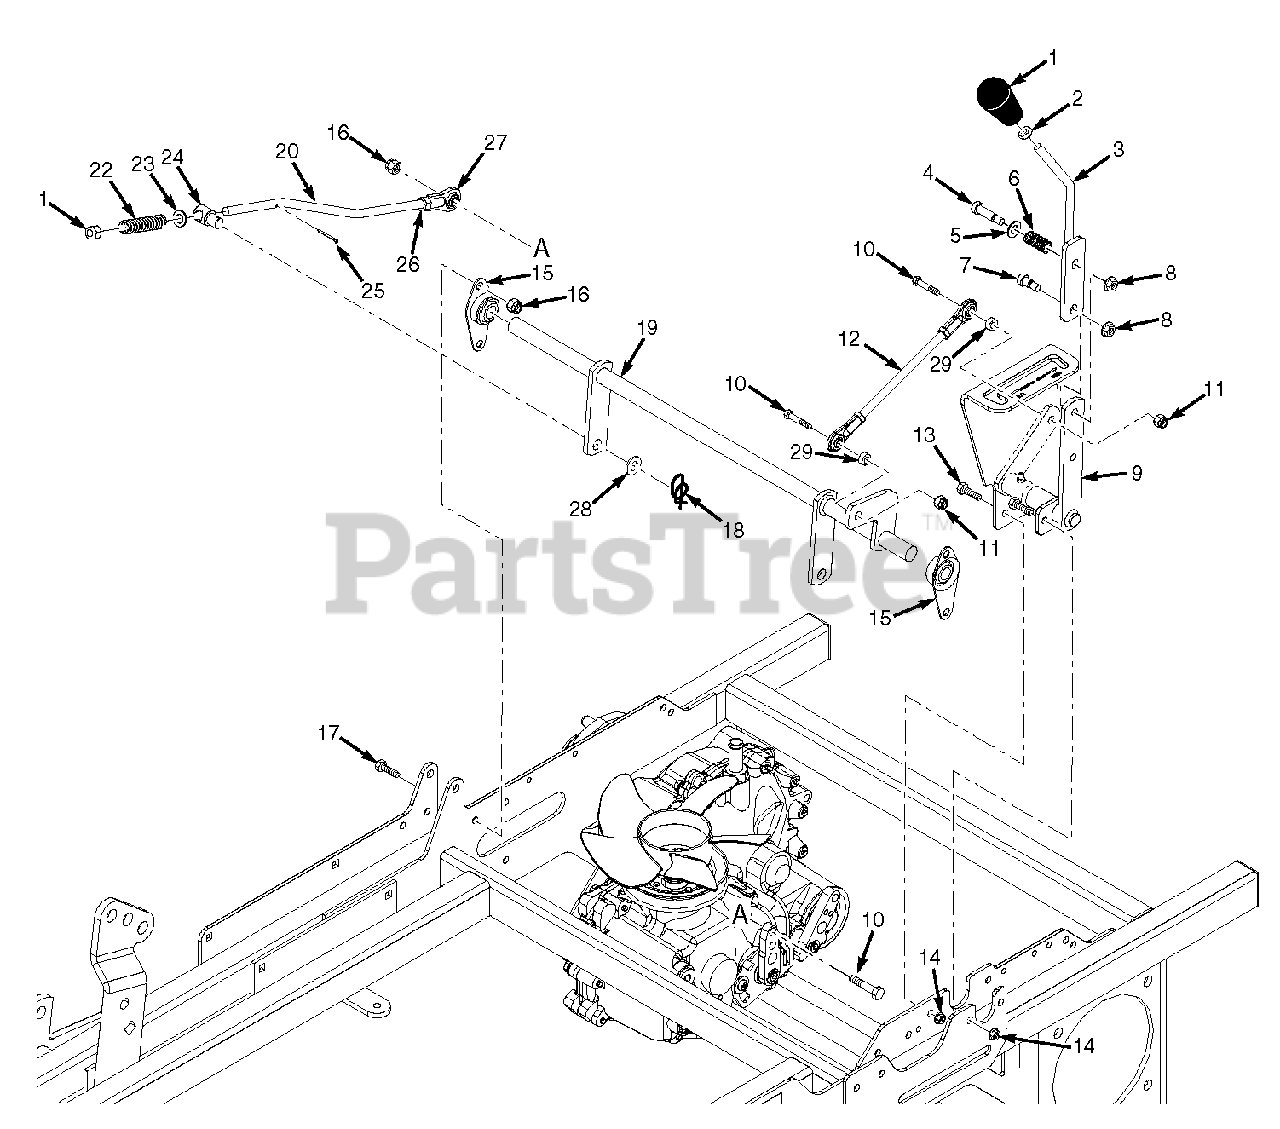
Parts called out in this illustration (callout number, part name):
1	Knob, Soft Touch
2	Nut, Jam 3/8-16 UNC
3	Lever Weldment, Speed Control SCZ
4	Bolt, Shoulder 3/8 x 1"
5	Flatwasher, 3/8-.406 x .812 x .065
6	Spring, Speed Control
7	Bolt, Shoulder 3/8 x 3/8"
8	Nut, Serrated Flange 5/16-18
9	Control Weldment, Speed Range Adjust
9	Grease Fitting, 1/4-28 Self Tap
10	Bolt, Hex Head 3/8-16 x 1-1/2"
11	Nut, Elastic Stop 3/8-16
12	Linkage Assembly, Upper Speed Control
12	Rod End, 3/8-24 RH
12	Nut, Jam 3/8-24 UNF
12	Rod End, 3/8-24 LH
12	Nut, Jam 3/8-24 UNF LH
13	Bolt, Hex Head 5/16-18 x 1"
14	Nut, Flange Head Elastic Stop 5/16-18
15	Bearing, Self Align
16	Nut, FLG HH Elastic Stop 5/16-18
17	Bolt, Hex Head 5/16-18 x 3/4"
18	Pin, Rue Cotter 1/2" Dia.
19	Speed Control Bellcrank Weldment
20	Rod, Speed Linkage
21	Nut, Elastic Stop 3/8-24
22	Spring
23	Flatwasher, 3/8-.406 x .734 x .063
24	Bushing, Pivot
25	Cotter Pin
26	Nut, 3/8-24 UNF Jam
27	Rod End, 3/8-24
28	Flatwasher, 3/8-.391 x .938 x .105
29	Spacer
